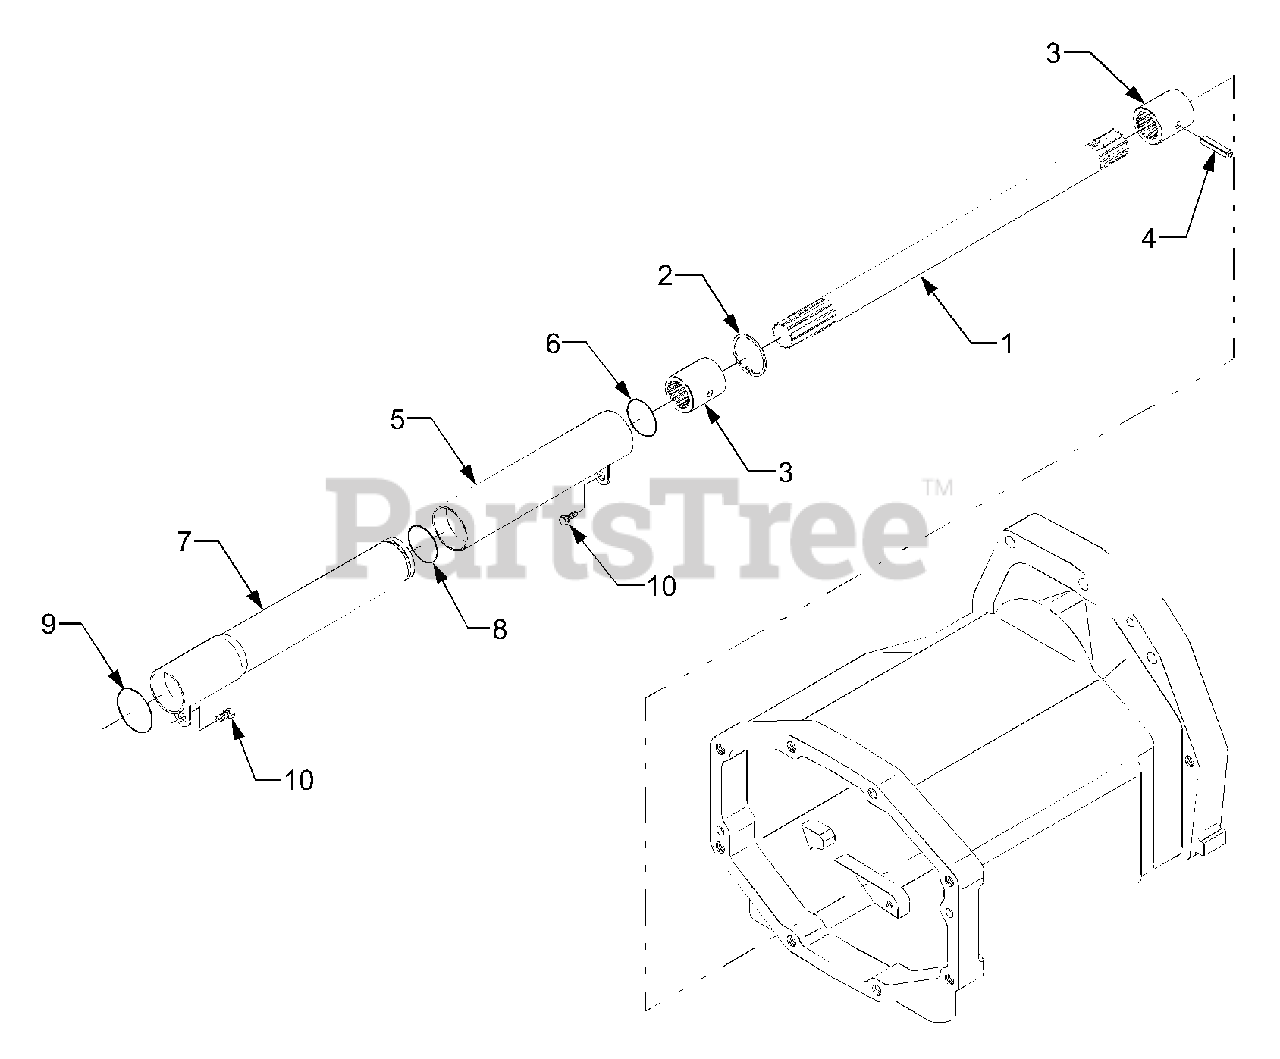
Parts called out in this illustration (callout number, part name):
1	Shaft 2, Propeller
5	Cover, Propeller
7	Cover 2, Propeller
